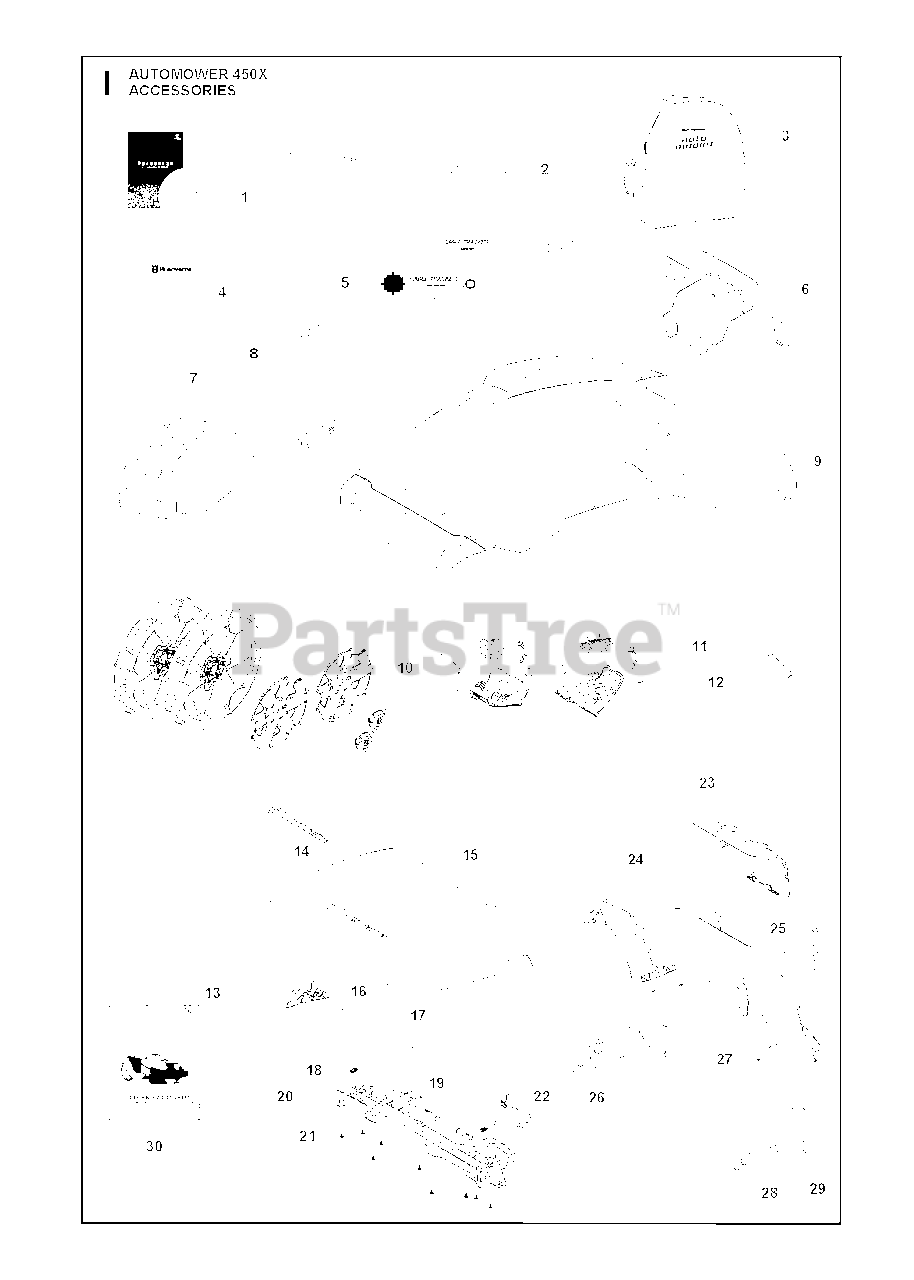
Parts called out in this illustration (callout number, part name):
1	DVD Autocheck, Exp Ser
2	CABLE WHITE ALT GREY
3	BAG
4	LABEL WARRANTY SEAL DEALER
5	TEST EQUIPMENT
6	MISC. BLISTER WALL HA
7	CHARGER BATTERY TEST
8	CABLE ASSY QUICK CHARGER
9	BODY KIT
9	Top Cover, White 450
9	TOP COVER ORANGE 450
10	BRUSH KIT 430450
11	Rear Wheel Kit with Brush
12	WHEEL BRUSH REFILL KIT
13	430450 HOUSE KIT
14	DECAL.HUSQVARNA.210MM
15	KIT LID - AUTOMOWER HOUSE
16	HANDLE RELEASE LEFT
17	ROD
18	SPRING SPRING CAP
19	HINGE PIN
20	BEAM
21	SCREW 14MM
22	HANDLE RELEASE RIGHT
23	HATCH
24	COVER BASE P2 HOUSE
25	SCREW KIT CS
26	SUPPORT BASE LEFT
27	NUT
28	SUPPORT BASE RIGHT
29	SCREW IHPANM M6X25 4.6 ZP-BC
